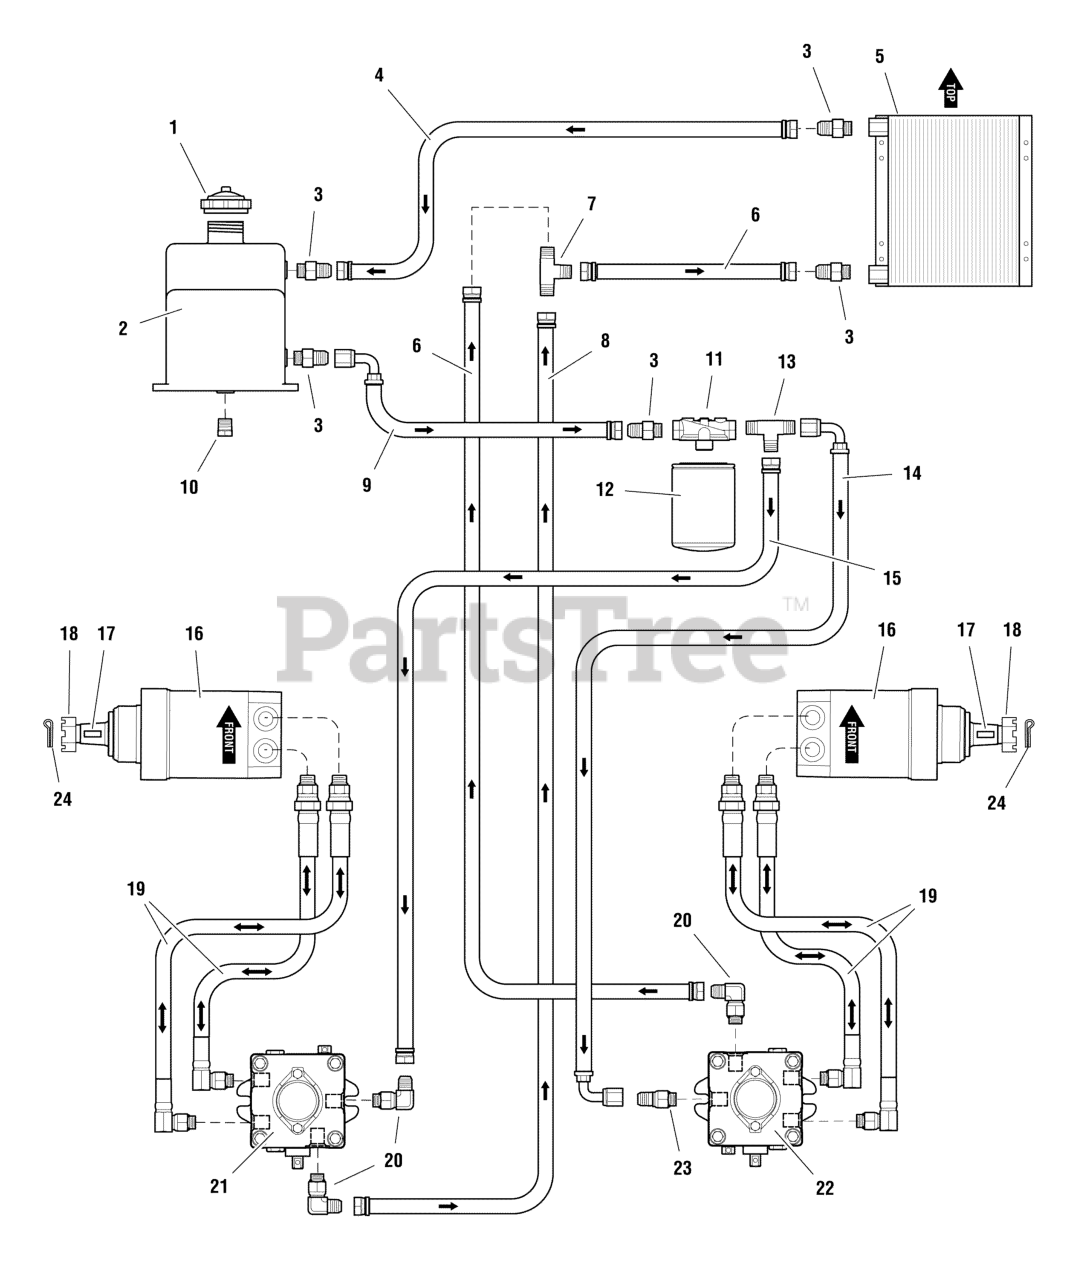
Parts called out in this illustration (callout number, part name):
1	CAP, Reservoir
2	HYDRAULIC OIL RESERVOIR
3	FITTING, NPT - JIC #8
4	HOSE ASSEMBLY (58")
5	OIL COOLER
6	HOSE ASSEMBLY (36")
7	FITTING, TEE, JIC #8
8	HOSE ASSEMBLY (15")
9	HOSE ASSEMBLY (9")
10	PLUG, 1/2" NPT
11	FILTER HEAD
12	FILTER, HYDRAULIC, SERVICE PART (PKG)
13	FITTING, TEE, JIC #8, NPT
14	HOSE ASSEMBLY (30")
15	HOSE ASSEMBLY (40")
16	HYDRAULIC WHEEL MOTOR, Complete
17	KEY
18	NUT, CASTLE, 1-20
20	FITTING, O-Ring, 90 Deg.
21	HYDRAULIC PUMP - LH
22	HYDRAULIC PUMP - RH
23	FITTING, O-Ring Adapter
24	PIN, COTTER, 1/8" X 2"
